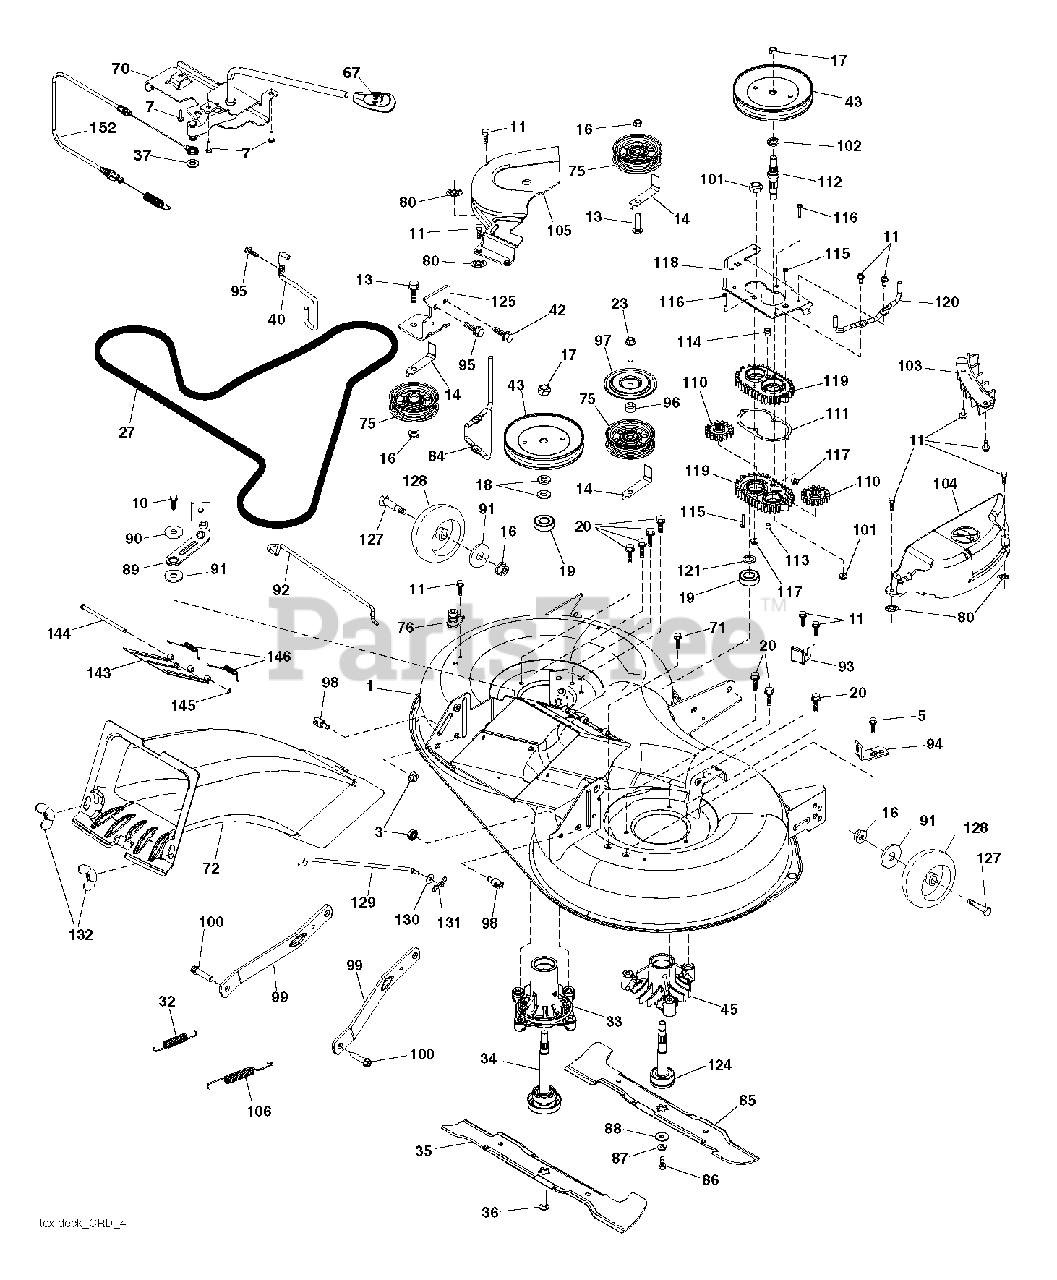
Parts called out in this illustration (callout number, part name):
1	DECK.WELDMENT.97.TEX.498
3	NUT LOCK HEX FLANGE 5/16-18
5	BOLT.5/16HEX.WHS.HD
7	SCREW.#10 X 0.750.BOS
10	SCREW 3/8-16X1
11	SCREW.1/4-20X5/8
13	BOLT.3/8-16X1.50
14	KEEPER, BELT IDLER
16	NUT LOCK FLG 3/8-16 UNC
17	NUT.FLANGE.LOCK.TOP
18	WASHER.SPACER.MANDREL
20	SCREW, WASHER HEAD
23	SCREW LT
27	BELT V-BELT DRIVE
32	SPRING RETURN
33	HOUSING.MANDREL.4PT.
34	SHAFT.ASM.MDRL.N/GREASE.38
35	BLADE.3N1.LH.CRD.97
36	BOLT.WASHER.ASM.7/16-2
37	WASHER
40	KEEPER BELT ENGINE LH
42	SCREW
43	PULLEY.MANDREL.5.438.PD
45	HOUSING.MANDREL.44/46" VENT
67	HANDLE.CLUTCH.CABLE.LT
70	CLUTCH.ASM.MANUAL.LT.PRED
71	SCREW 3/8-16X1/2
75	FLAT IDLER PULLEY
76	PORT.WASHOUT
80	PALNUT 1/4
84	KEEPER.BELT.MANDREL.PULLEY
85	BLADE.3N1.RH.CRD.97
86	BOLT.3/8-24X1.25GR8. LHTHRD
87	LOCKWASHER
88	WASHER.BLADE
89	ARM.BRAKE.97.LH
90	SPACER.RETAINER
91	WASHER
92	ROD ROD BRAKE
93	ARM.BRAKE.97.RH
94	BRKT.CLUTCH.CABLE
95	SCREW, 3/8-16X3/4
96	SPACER
97	PROTECTOR
98	STUD.FASTNER.W/ANTI-ROTATE
99	ARM.SUSPENSION.MOWER.R
100	BOLT.SHOULDER
101	NUT.CROWNLOCK.9/16 -18.UNC
102	SPACER BEARING
103	GUARD GUARD FRONT VENT
104	97.CRD.RH.MANDREL.COVER
105	MANDREL MANDREL COVER LH
106	SPRING.BRAKE.RETURN.38"
110	GEAR GEAR OUTPUT
111	GASKET GASKET GEARCASE
113	PLUG PLUG OIL
114	VALVE VALVE RELIEF
115	SCREW
116	BOLT.CARIGE.SS.1/4-20X1.75GR5
117	NUT T
118	ARM ARM CLUTCHING
119	GEARCASE GEARCASE SUBASM
120	BRACKET KEEPER BELT RH
121	WASHER WASHER
124	MANDREL SHAFT NON/GREASE
125	BRACKET BRACKET IDLER CHASSES
127	BOLT.SHOULDER.3/8-16X3-5/8.
128	WHEEL. GUAGE RALLY
129	ROD.ANTI.SWAY.48/54"K4
130	WASHER
131	PIN.COTTER.5/16.BOW TI
132	KNOB.HANDLE.3/8.TRI-POINT.BLAC
143	DOOR
144	PIN PIN.HINGE
145	E-RING.5/16"
152	CABLE CABLE CLUTCH MANUAL W/S
